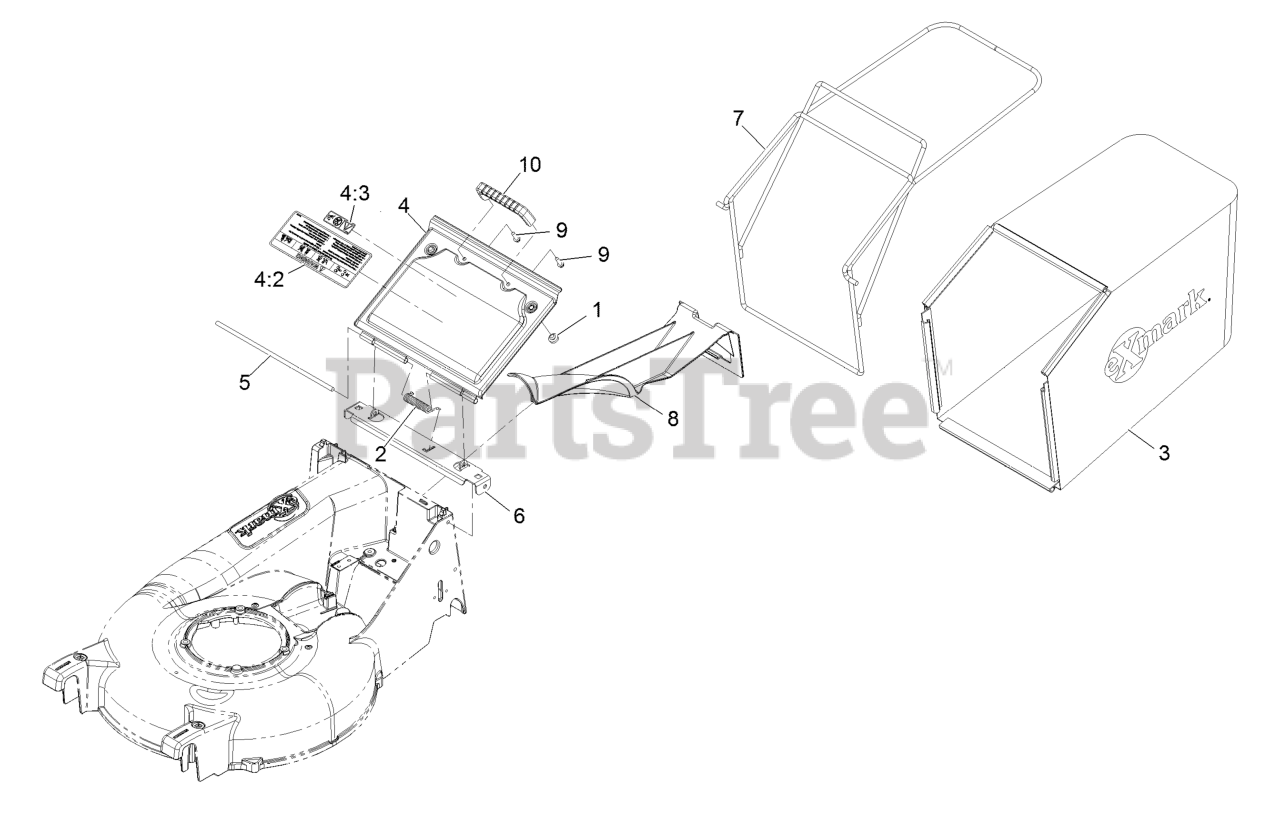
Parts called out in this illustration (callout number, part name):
2	SPRING-TORSION,COVER
3	BAG,GRASS P21
4	DOOR W/DECAL
4:2	DECAL-WARNING DOOR LG
4:3	DECAL-WARNING, BLOCK
5	ROD,DOOR PIVOT
6	BRACKET-DOOR P21
7	WLD,BAG FRAME
8	PLUG,MULCH
9	SCREW-HWH
10	HANDLE-DOOR
